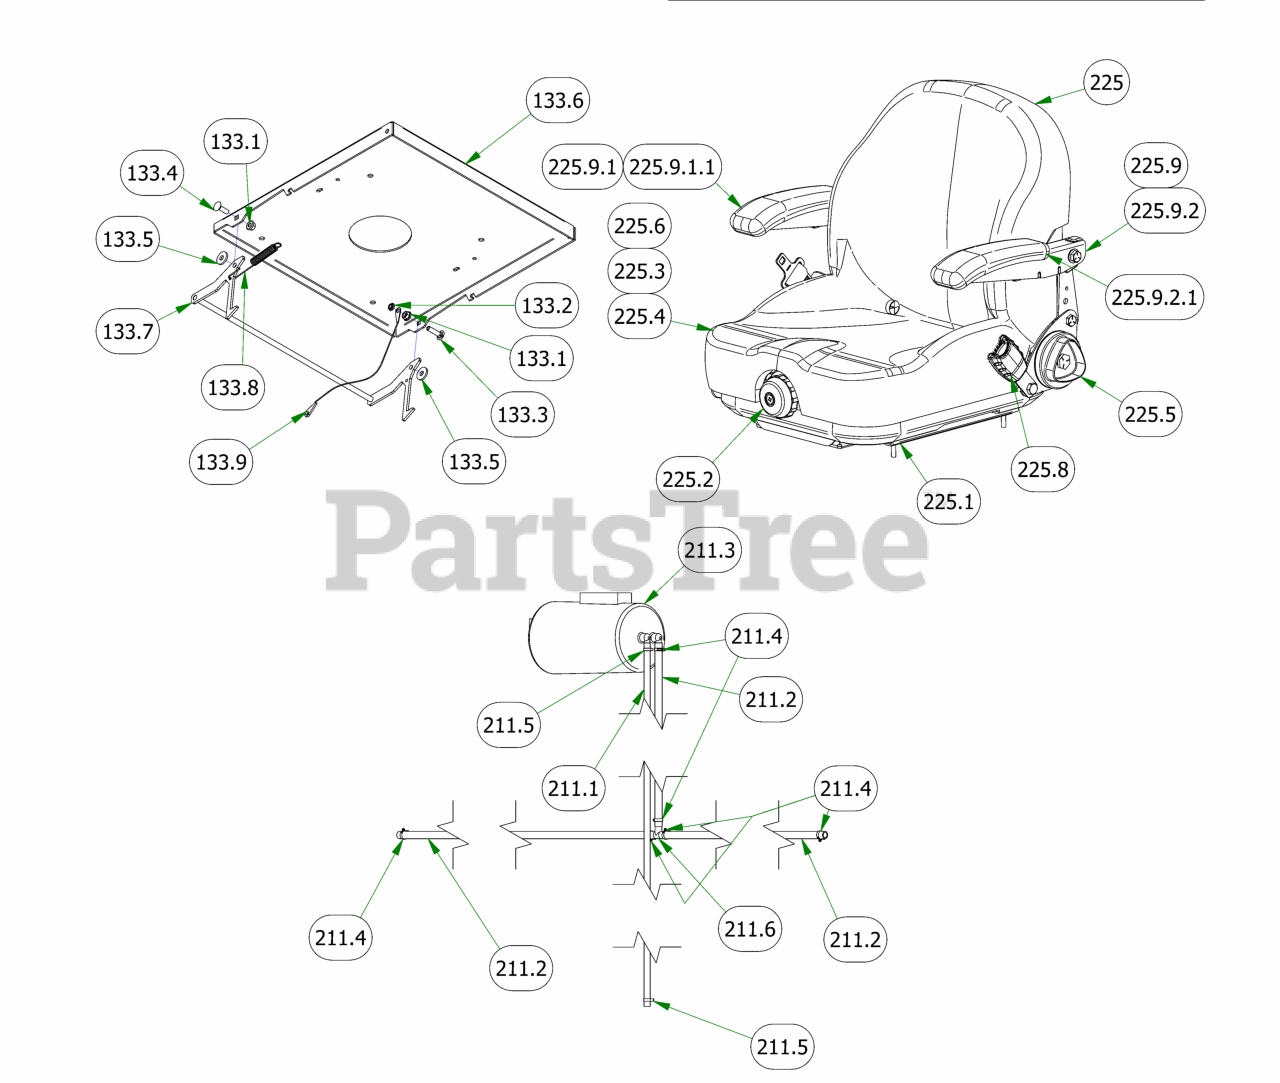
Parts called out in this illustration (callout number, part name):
133	R-SERIES SEAT PLATE ASSEMBLY
133.1	5/16-18 NYLON INSERT FLANGE LOCKNUT ZINC
133.2	5/16-18 NYLON INSERT JAM LOCKNUT ZINC
133.3	5/16-18 X 1-1/4 CARRIAGE BOLT ZINC
133.4	5/16-18 X 1 CARRIAGE BOLT (GR.8) ZINC
133.5	.360 ID X .983 OD X .120 THICK FLAT WASHER NYLON
133.6	R-SERIES SEAT PLATE
133.7	Seat Latch Rod Assembly
133.8	Brake Spring
133.9	Seat Cable
211	2019 Outlaw EPA Cannister Assembly
211.1	3/16" Vinyl Tubing, 66" Long
211.2	1/4" Vinyl Tubing 38" Long
211.3	Carbon Canister
211.4	3/16 Vinyl Clamp
211.5	3/16" Vinyl Hose Clamp
211.6	fuel line T
225	2022 Suspension Seat w/Seatbelt
225.1	4" Single Locking Track Kit
225.2	Weight Adjust Indicator Knob Assy
225.3	Bellows w/Hardware
225.4	Cushion Cover Kit for I3M-Logo
225.5	Recliner Adjustment Knob-New
225.6	Delta Plunger Switch - N.O.
225.7	Back Cover for I3M - Recl - Logos
225.8	2" Retractable Belt Kit w/Spacers
225.9	Set of Armrests-SS Front Adj
225.9.1	RH Armrest-Selfskin Front Adj
225.9.1.1	Black Selfskin-Arm Pad Only
225.9.2	LH Armrest-Selfskin Front Adj
225.9.2.1	Black Selfskin-Arm Pad Only
